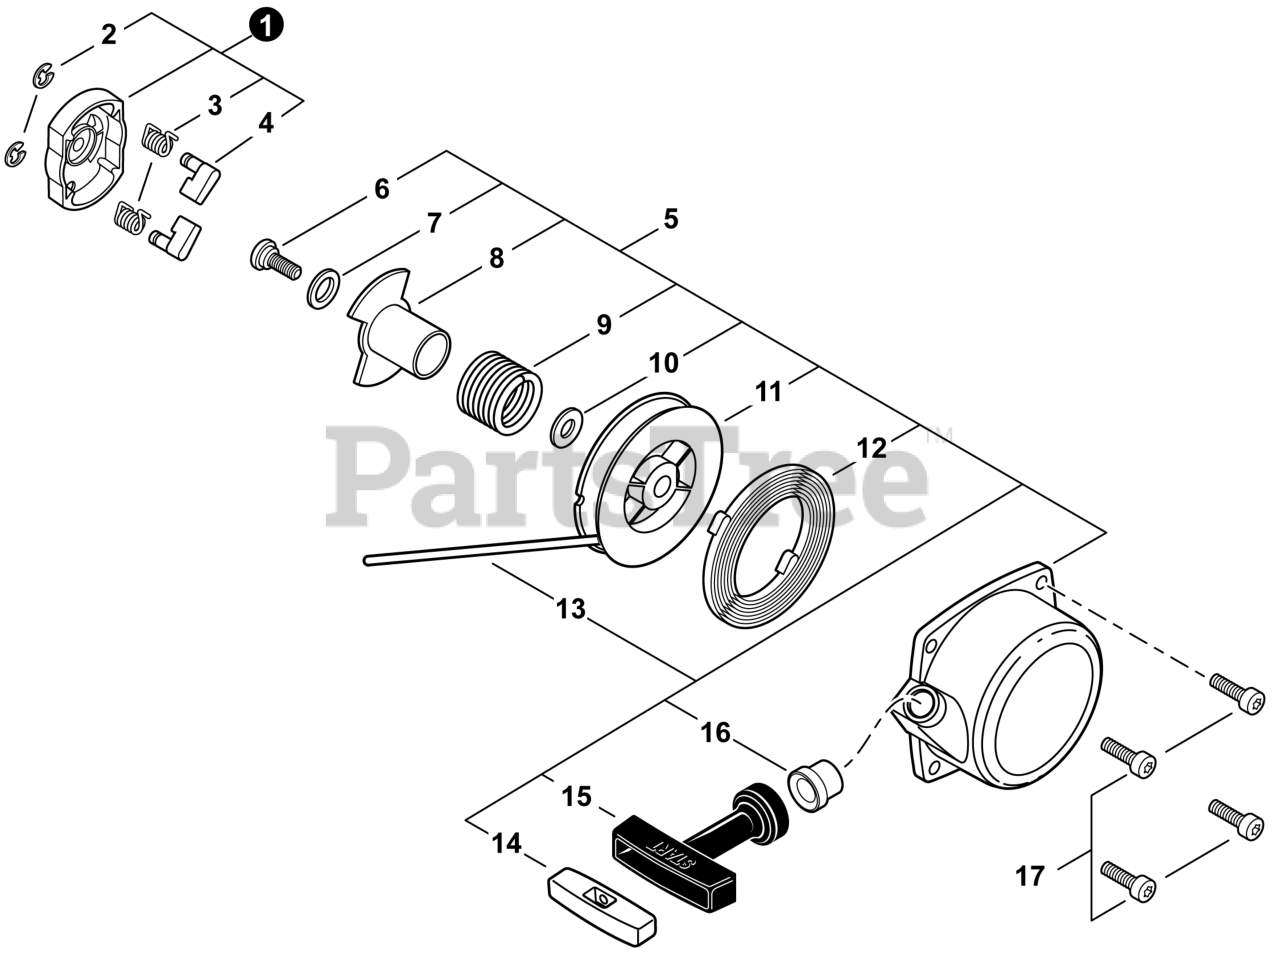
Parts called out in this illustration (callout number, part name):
1	PULLEY ASSY, STARTER
2	E-RING 4
3	SPRING, RETURN
4	PAWL, STARTER
5	STARTER ASSY, RECOIL
6	SCREW
7	WASHER, THRUST
8	PAWL CATCHER
11	REEL, ROPE
12	SPRING, RECOIL
13	ROPE, STARTER 3.5×1000 MM
14	RETAINER, ROPE
15	GRIP, STARTER
16	GUIDE, ROPE
17	SCREW 5×16
